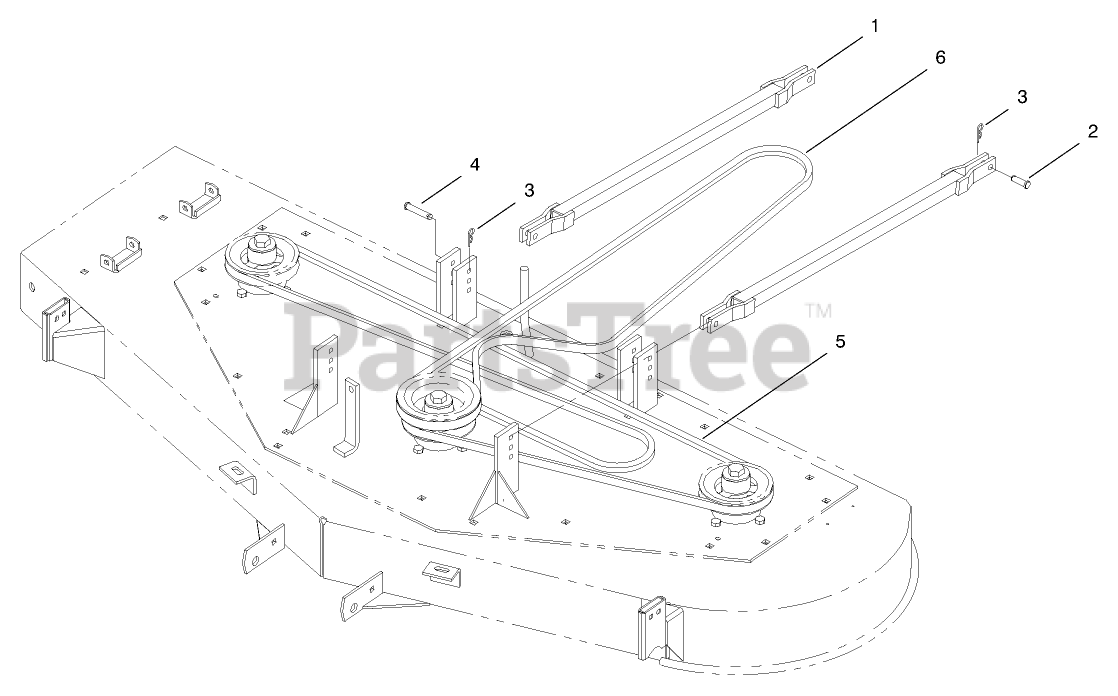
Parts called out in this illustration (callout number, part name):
1	BAR-STABILIZER WA B
2	CLEVIS PIN3/8X1 1/4
3	HAIRPIN
4	CLEVIS PIN
5	BELT-V
6	V-BELT, 60" DECK
